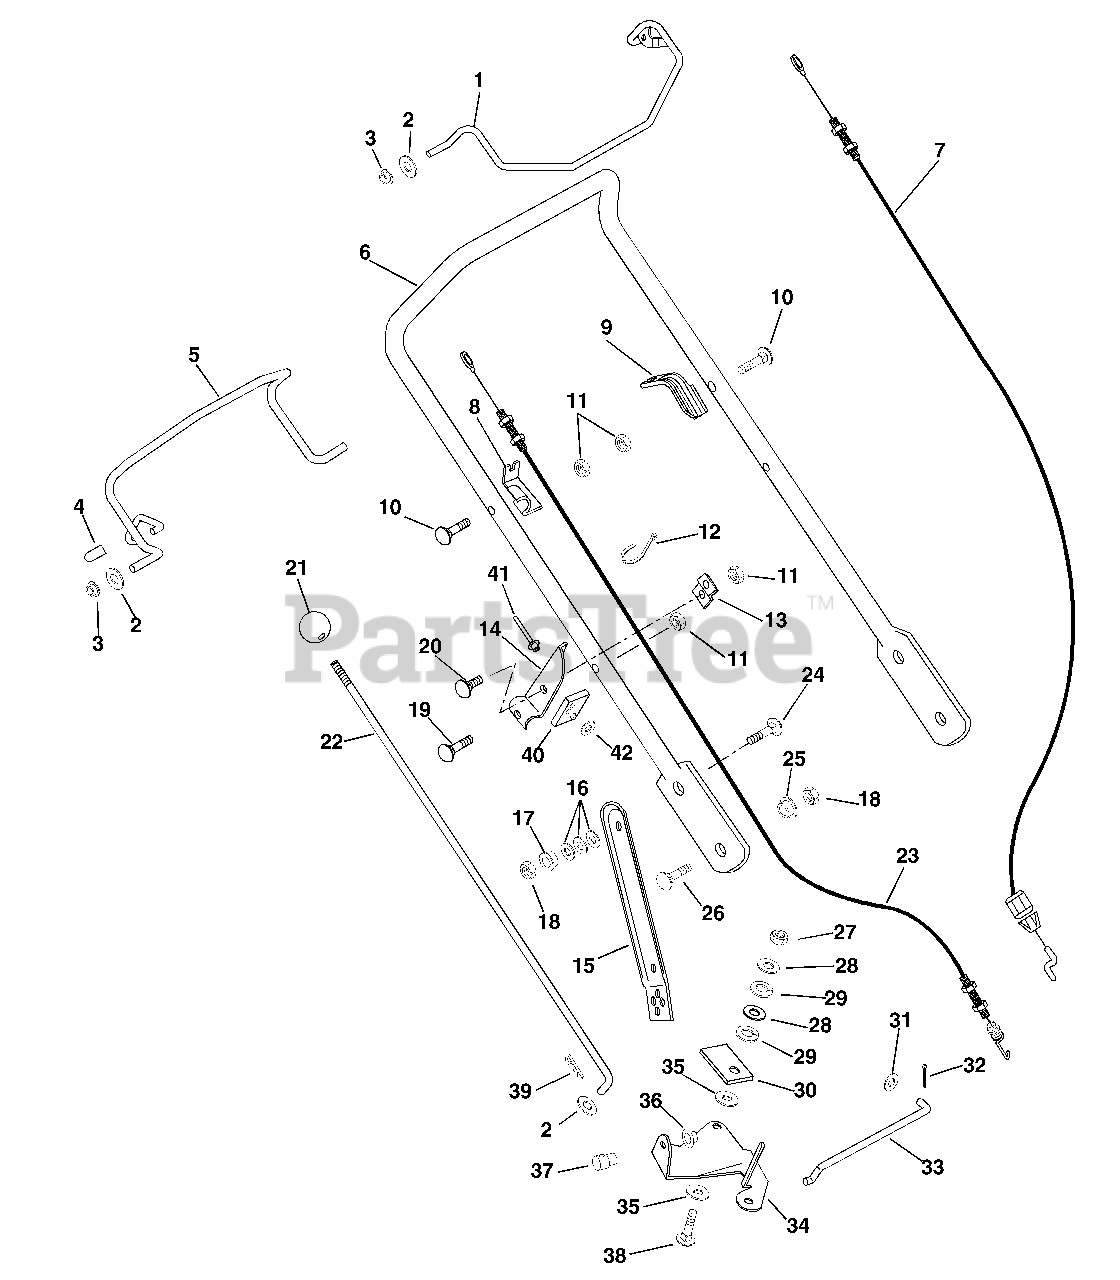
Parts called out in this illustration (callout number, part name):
1	ENGINE BAIL
2	@WSHR-FL-STL.344X.688X.065YWZC
3	BSHG-FLG .325X.444X.440X.560
4	CAP, VINYL, .25 ID
5	TRACTION BAIL
6	HANDLEBAR, SELF-PROPELLED
7	ENGINE CONTROL CABLE
8	ANCHOR, CABLE RH
9	CABLE ANCHOR-LH
10	BLT-RDHDXLSQNK.25-20X1.25 G5ZC
11	@NUT-LK-CTR .25-20 YWZC
12	CABLE TIE LG 5-1/2
13	BRACE, SPEED CONTROL
14	BRACKET, SPEED CONTROL
15	LINK, HANDLEBAR ADJUSTMENT LH
15	LINK, HANDLEBAR ADJUSTMENT RH
16	WASHER, BELLEVILLE YWZC
17	BSHG-FLG .325X.500X.513X.875
18	@NUT-LK-CTR .31-18 YWZC
19	@BLT-RDHDSQNK .25-20X1.50 G5YZ
20	@BLT-RDHDSQNK .25-20X.50 G5YZ
21	KNOB, BALL 5/16-18 X 1.5
22	ROD-SPEED CONTROL
23	TRACTION CABLE
24	@BLT-RDHDSQNK .31-18X1.00 G5YZ
25	BSHG, FLG .325X.499X.26X.88
26	@BLT-RDHDSQNK .31-18X.75 G5YZ
27	@NUT-LK-CTR .38-16 YWZC
28	@WSHR-FL-STL.406X.812X.065 YWZ
29	WSHR-LK .375X.115 HVY YWZC
30	PRESSURE FLANGE
31	@WSHR-FL-STL.281X.62X.065 YWZC
32	@PIN-CTR .06X.50 EXTPRSQCT YWZ
33	SHIFT LINK
34	BELL CRANK - SPEED CONTROL
35	FRICTION WASHER
36	CAP, 3/8 ROD YWZC
38	@BLT-RHDSSQNK .38-16X1.25 G5YZ
39	PIN-HAIR INT .08X.18X1.18 YWZC
40	SUPPORT PAD
41	RVT .187X.575 DOME AL BLACK
42	@WSHR-FL-STL.219X.50X.049 YWZC
